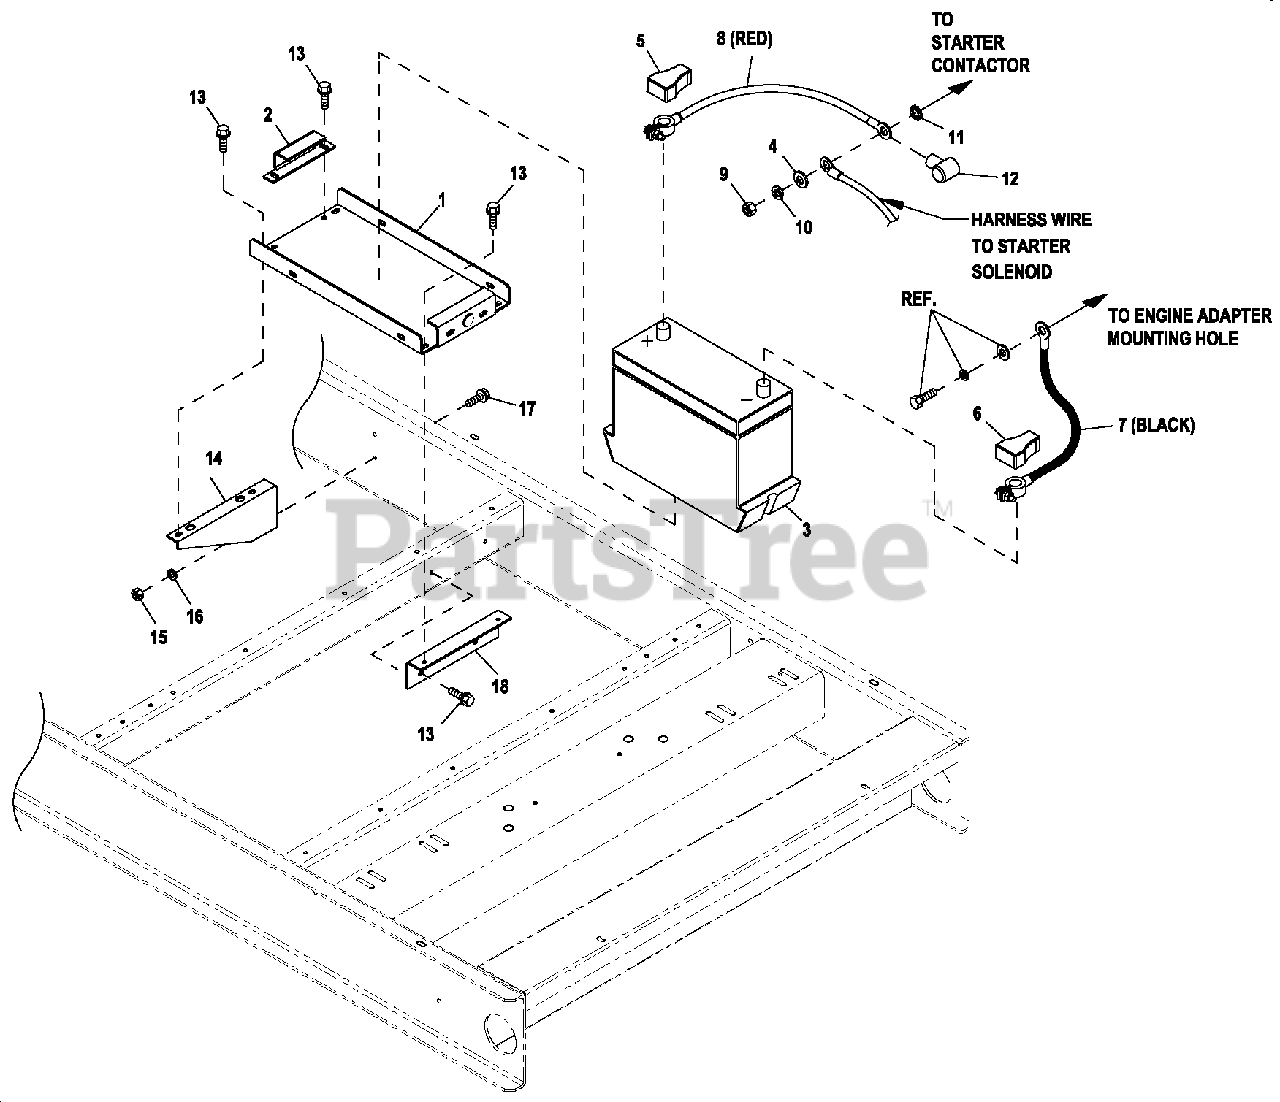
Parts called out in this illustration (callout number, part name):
1	TRAY BATTERY 27F
2	STRAP BATTERY RETAINMENT 27F
3	BATTERY 12VDC 90-AH27F
4	WASHER F LAT 3/8-M10 ZINC
5	BATTERY POST COVER RED +
6	BATTERY POST COVER B LK -
7	CAB LE BATTERY BAC LK #1 X 26.00
8	CAB LE BATTERY RED #1 X 28.00
9	NUT HEX M8-1.25 G8 YE LCHR
10	WASHER LOCK M8-5/16
11	WASHER SHAKEPROOF EXT 5/16 ST
12	BOOT BATTERY CAB LE
13	SCREW THF M6-1 X 16 N WA Z/JS
14	SUPPORT BATTERY TRAY
15	WASHER LOCK M6-1/4
16	NUT HEX M 6X1.0 G8 YELCHR
17	SCREW HHC M6-1.0X20 G8.8
18	SUPPORT 27FBATTERY
